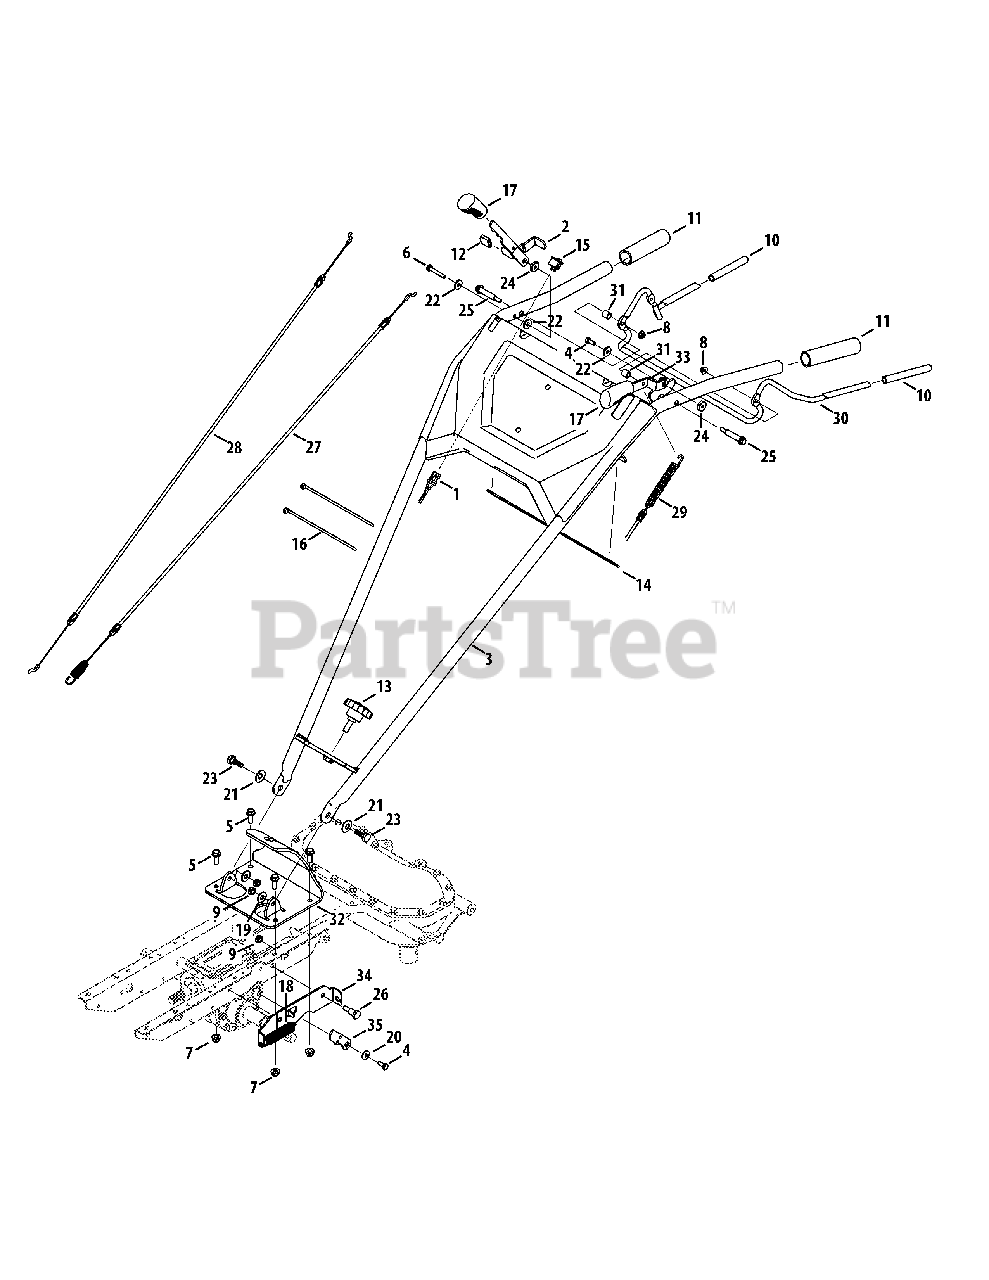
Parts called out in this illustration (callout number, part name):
1	Harness Assembly Adapter
2	Reverse Handle Assembly
3	Handle Assembly
4	Hex Screw, 1/4-20 x .625
5	Hex Head Washer, 5/16-18 x .875
6	Hex Head Screw, 1/4-20 x 1.62
7	Flangelock Nut, 5/16-18
8	Flangelock Nut, 1/4-20
9	Hex Lock Nut, 5/16-18
10	Clutch Grip
11	Grip, 1.0 x 5.0
12	Reverse Handle Grip
13	Star Knob, 3/8-16
14	Foam Tape, 1.25 x 13.53 x .10
15	Rocker Switch
16	Cable Tie, 8.5 LG
17	Reverse Handle Grip
18	Extension Spring
19	Flat Washer, .349 x .879 x .063
20	Bell Washer .265 x 0.75
21	Bell Washer, .45 x 1.00 x .062
22	Washer, Flat, .250 x .750 x .119
23	Shoulder Screw, 5/16-18 .437 x .268
24	Spacer, .375 x .165
25	Shoulder Screw, 1/4-20 .375 x 1.62
26	Shoulder Screw, .437 Dia. x .54
27	Forward Cable
28	Reverse Cable
29	Neutral Cable
31	Spacer, .383 x .500 x .535
32	Height Adjustment Mounting Plate
33	Neutral Handle
34	Neutral Cable Frame Bracket
35	Neutral Pivot Lever
